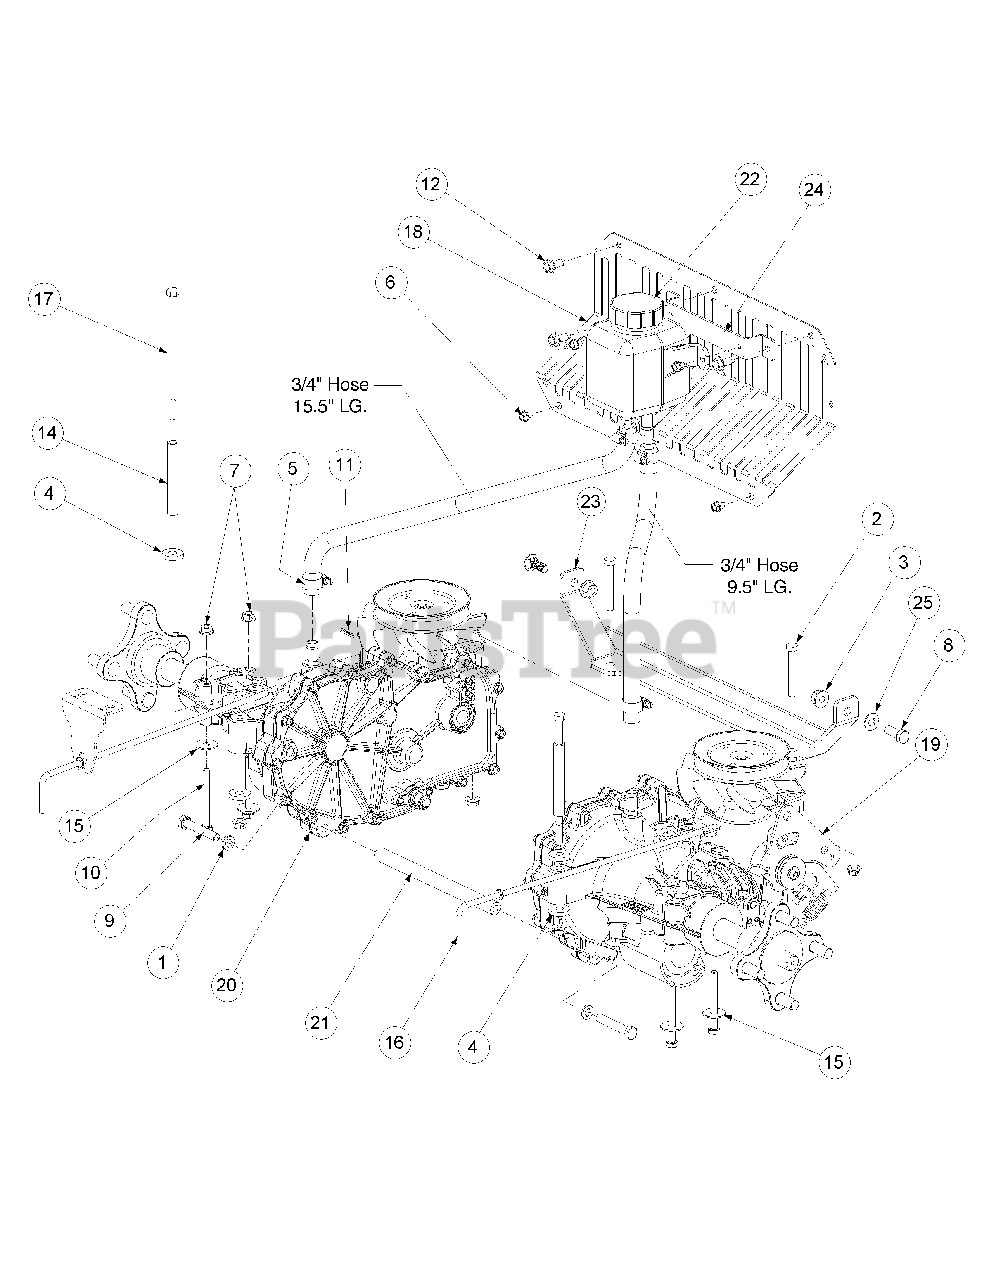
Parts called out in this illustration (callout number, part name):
1	Lock Washer, 3/8
2	Hex Cap Screw, 5/16-18 x 2.25
3	Flange Lock Hex Nut, 3/8-16
4	idler Washer
5	Hose Clamp
6	Screw, TT, 1/4-20 x .5, Hex Index Washer
7	Hex Flange Lock Nut, 5/16-18
8	Hex Cap Screw, 3/8-16 x 1
9	Hex Cap Screw, 3/8-16 x 2.25
10	Hex Cap Screw, 5/16-18 x 2.75
11	Cotter Pin, .072 x 1.12 Long
12	Self Tapping Screw 5/16-18 x .750
13	Hose, .50 ID x .75 OD (25 inches)
14	Spacer, .370 ID x .500 OD x 3.45
15	Washer, 5/16 x 1.06
17	Hex Cap Screw, 5/16-18 x 6.00
18	Pump Screen
19	Transmission Assembly, RH includes:
19	Filter
20	Transmission Assembly, LH includes:
20	Filter
21	Transmission Support Tube
22	Hydraulic Tank
23	Transmission Brace Weldment
24	Hydraulic Tank Bracket
25	Flat Washer, 3/8
